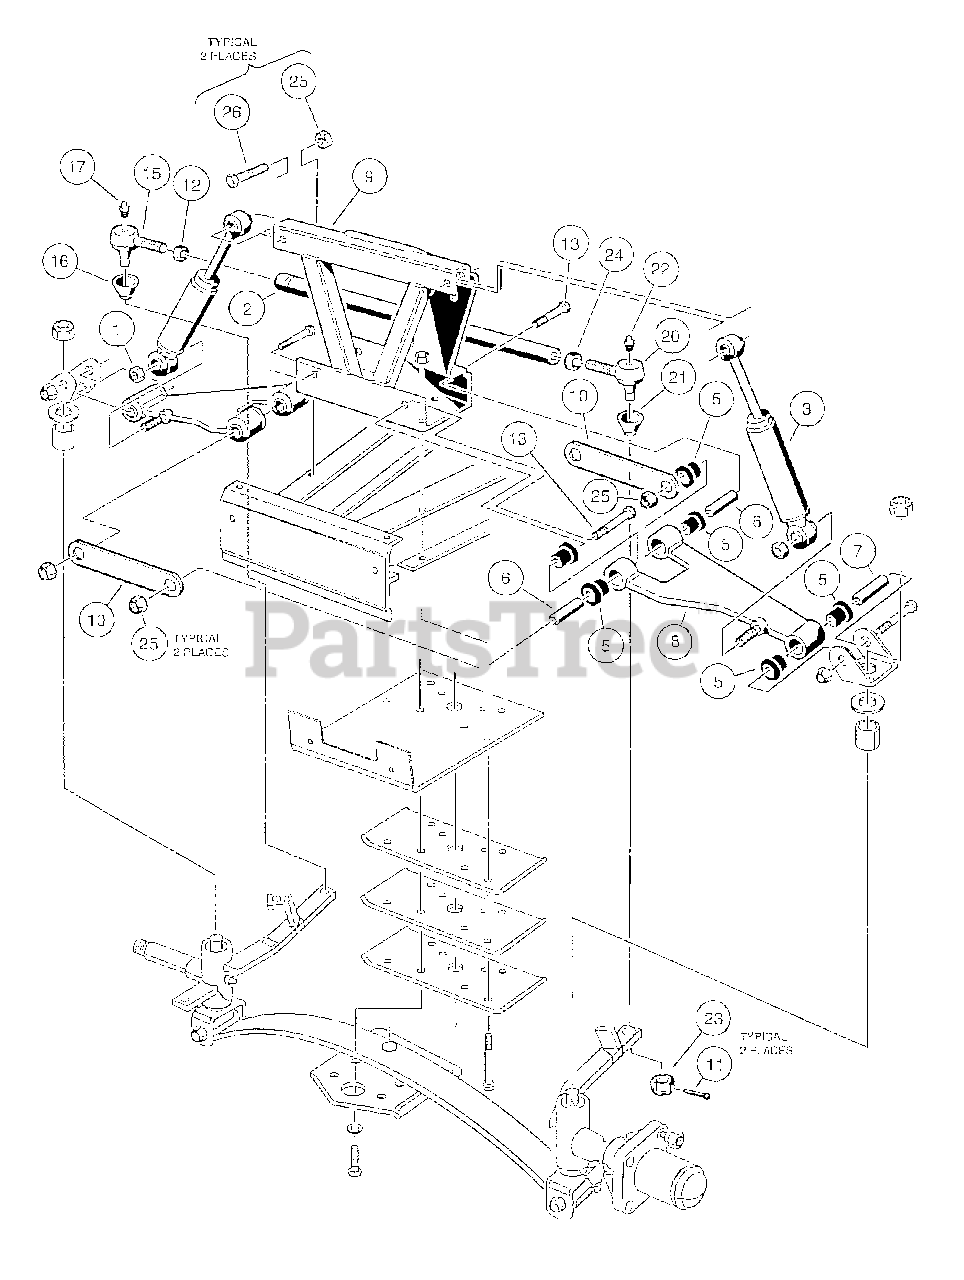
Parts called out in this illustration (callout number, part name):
1	Locknut, 3/8-16 Dimpled
2	Tie Rod
3	Shock Absorber
4	Sub-Assembly, Delta A-Plate
5	Bushing, Urethane
6	Sleeve, Delta Inner
7	Sleeve, Delta Outer
8	Detla A-Plate
9	Delta Shock and Gear Support Assembly
10	A-Plate Strap
11	Pin, 3/32 X 1.00 Sq Cut Cotter
12	Nut, 1/2-20 Hex
13	Screw, 3/8-16 X 2.25 Hx Hd Cap
14	Ball Joint, Right-Hand
15	Socket, RH Vertical
16	Seal, Vertical Socket Dust
17	Fitting, 1/4-28 Thread-Forming Grease
18	Nut, 3/8-24 UNF Hex
19	Ball Joint, Left
20	Socket, LH Vertical
21	Seal, Vertical Socket Dust
22	Fitting, 1/4-28 Thread-Forming Grease
23	Nut, 3/8-24 UNF Hex
24	Nut, 1/2-20 Hex, Left-Hand Thread
25	Locknut, 3/8-16 Hex
26	Bolt, 3/8-16 X 1.75 Hex
